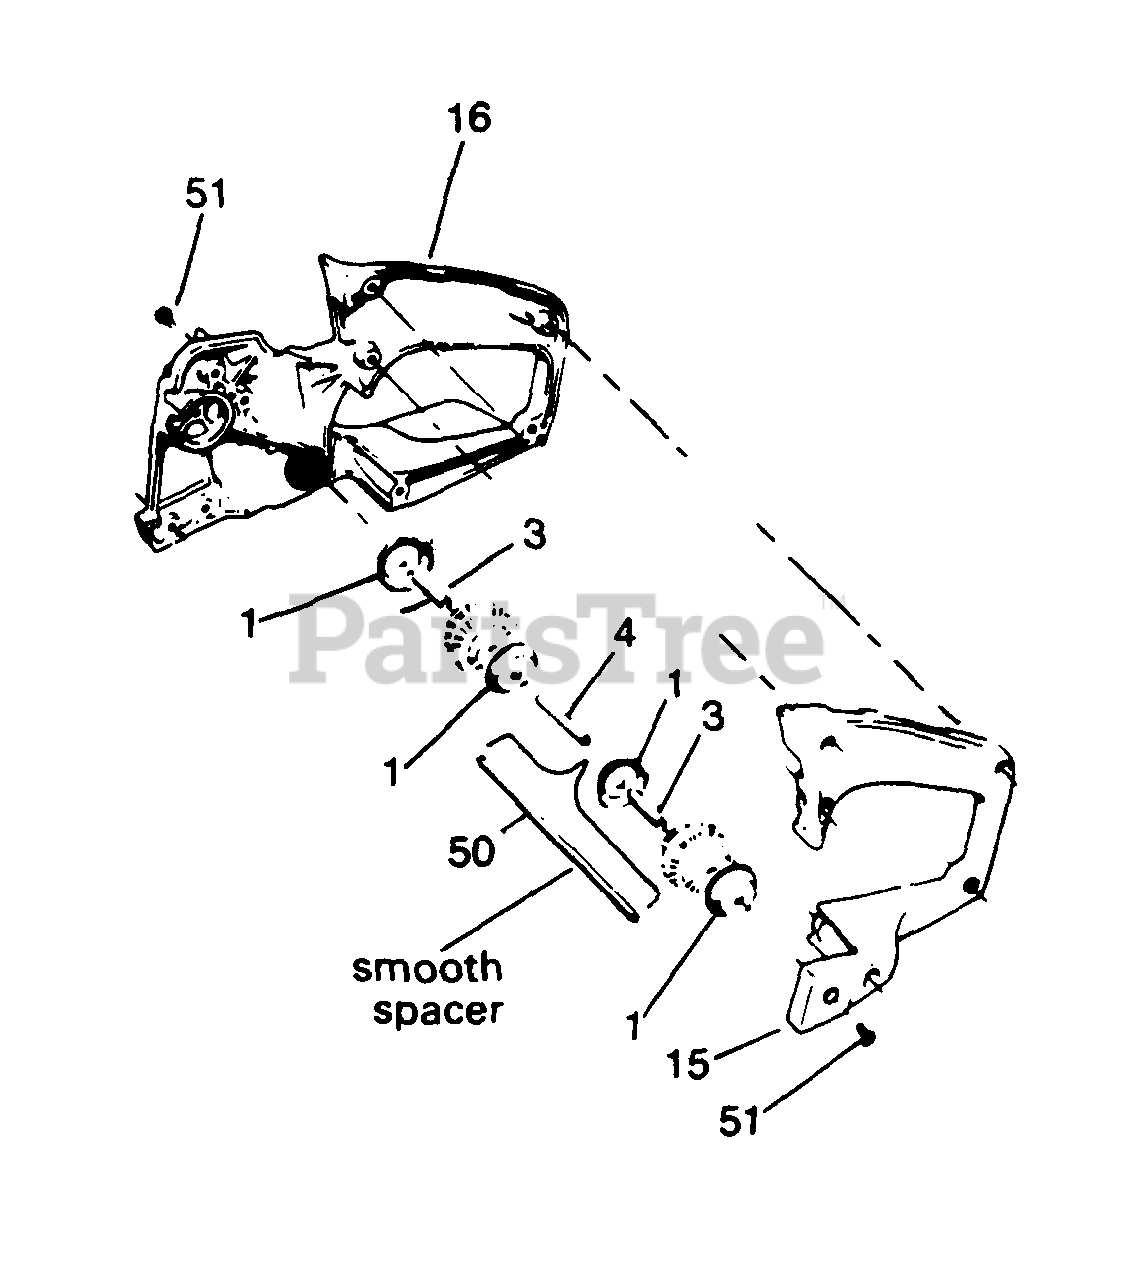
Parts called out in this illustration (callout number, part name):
1	Cup Isolator
3	Spacer Isolator
4	Spacer Isolator
6	Handle Brace
6	Use on Guide Bar Powerhead
6	Use on Bow Guide Powerhead
7	Screw - 10-24x9/16 Fil Hd.
15	Rear Handle-Left
16	Rear Handle-Right
50	Pin-Rear Isolator
51	Screw - 10-24 x 3/8 Pan Head
